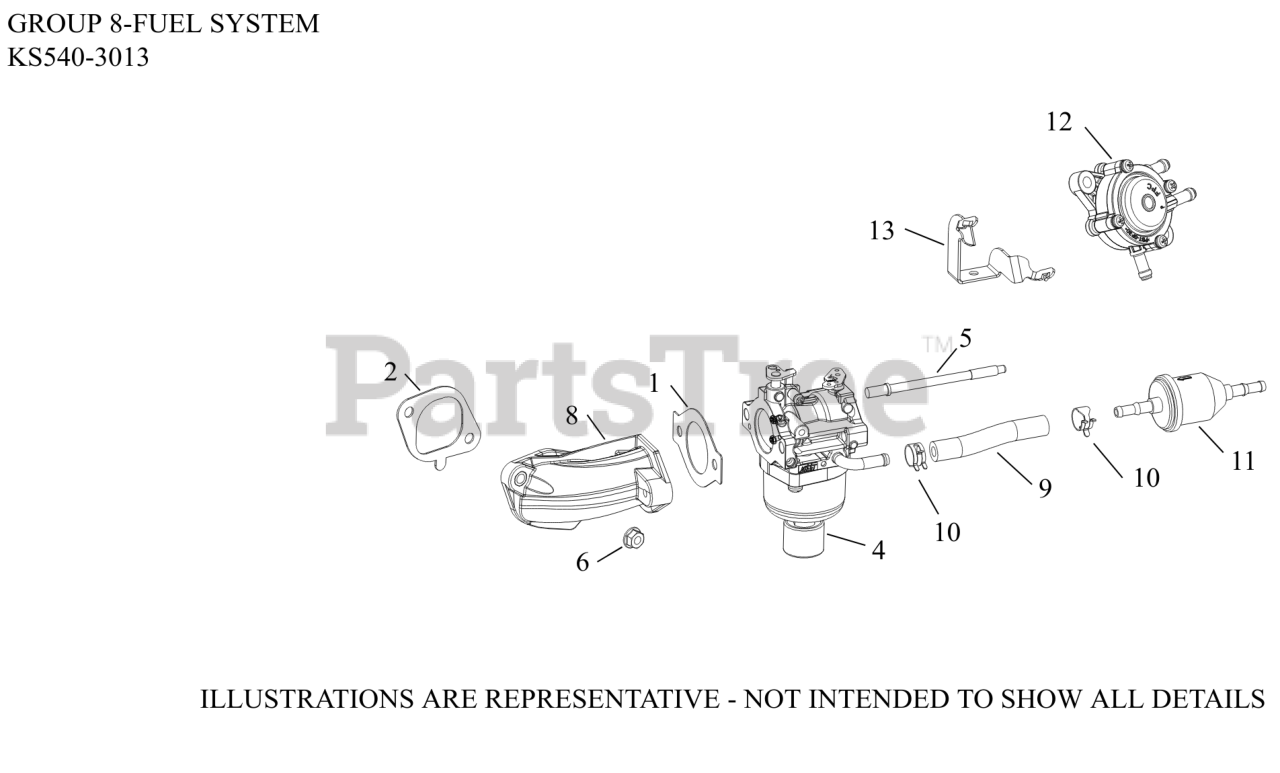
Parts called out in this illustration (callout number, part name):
1	GASKET, CARBURETOR (THROTTLE)
2	GASKET, INTAKE MANIFOLD
4	KIT,CARB(NIKKI)
5	STUD, CARBURETOR
6	NUT, FLG M6X1.0
8	MANIFOLD, INTAKE ASSEMBLY
9	HOSE,LW PERM.FUEL 24.00"-USE 25 111 81-S
10	SPRING CLAMP, HOSE
11	FILTER,FUEL 51 MICRON (FUEL PUMP)
12	PUMP, FUEL (PULSE)-(#2539326S)
13	BRACKET, FUEL PUMP
NI	HIGH ALTITUDE KIT (5000 FT)
NI	KIT, OVERHAUL
NI	KIT, CHOKE SHAFT
NI	KIT, O-RING
NI	KIT, SOLENOID (NIKKI)
NI	KIT, BOWL WITH O-RINGS
NI	KIT, FLOAT & INLET NEEDLE FOR FUEL PUMP
NI	KIT, THROTTLE SHAFT
